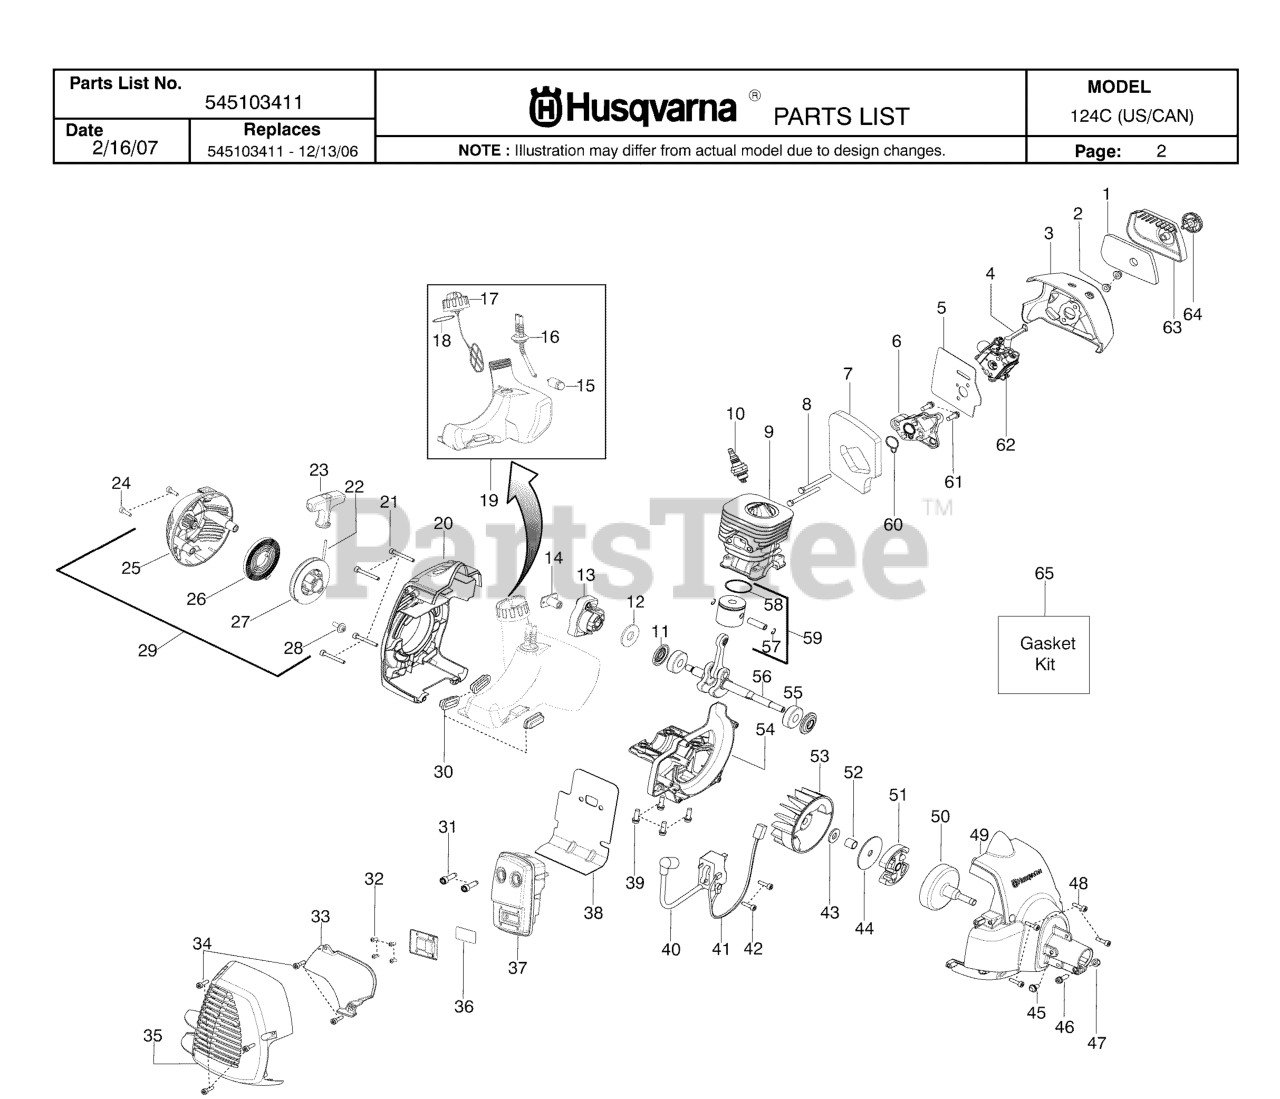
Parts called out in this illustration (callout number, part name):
1	FILTER AIRBOX
3	Air Box
4	CHOKE LEVER
5	KIT GASKET CARB
6	CARB ADAPTOR
7	KIT GASKET 28CC TRIMMER
8	BOLT CARB ADAPTOR
9	CYLINDER
10	Plug-Spark
11	KIT SEAL CRANKSHAFT
12	WASHER FLAT
13	ASSY-STARTER CUP
14	COUPLING-STARTER
15	FUEL PICK-UP ASSY
16	KIT FUEL LINE
17	ASSY-CAP W/RETAINER
18	O RING NITRILE
19	ASSY FUEL TANK FL
20	REAR SHROUD
23	STARTER HANDLE GRAY
24	SCREW M5-0.8X30MM
25	STARTER HOUSING
26	%KIT STARTER SPRING
27	KIT STARTER PULLEY
29	ASSY-STARTER HSG.
30	ISOLATOR FUEL TANK
31	BOLT MUFFLER
32	SCREW-10-16 X 1/2 HI-LO
33	SHIELD HEAT
34	SCREW M4 X 1.75 PT 16MM
35	GUARD-MUFFLER
36	KIT SPARK ARRESTOR SCREEN
37	ASSY-MUFFLER
38	GASKET PAPER METAL
39	SCREW-M5-0.8 X 25MM(TAP)
40	IGNITION MODULE MB45
41	ASSY MODULE LEAD WIRE
42	SCREW M4 X .70 TT 16MM
44	WASHER-CLUTCH
47	LOCKNUT-HEX 10-24
48	SCREW M4 X .70 TT 16MM
49	FAN HSG ASSY
50	Assy-Clutch Drum
51	%KIT CLUTCH ASSY
52	SPACER FLYWHEEL
54	CRANKCASE CASTING
55	BEARING RADIAL BALL (6201)
56	KIT CRANKSHAFT ASSY
57	WRIST PIN RET.
58	RING PISTON
59	KIT PISTON 28CC TRIMMER
60	KIT GASKET 28CC TRIMMER
61	SCREW-M5-0.8 X 25MM(TAP)
62	CARBURETOR
63	COVER-AIR BOX
64	KNOB ASSY AIRBOX COVER
65	KIT GASKET 28CC TRIMMER
